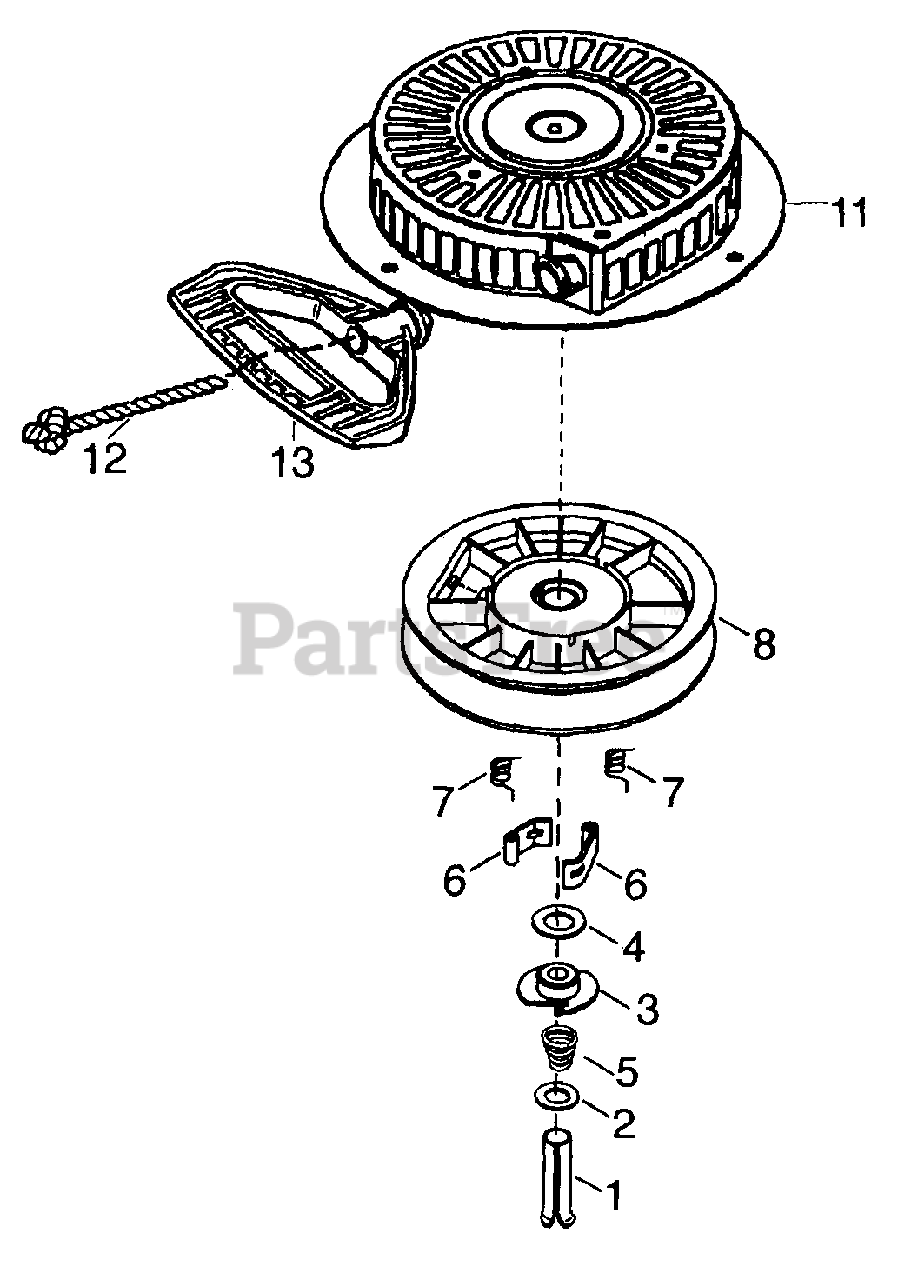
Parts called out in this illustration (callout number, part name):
5	Brake Spring
6	Starter Dog
7	Dog Spring
8	Pulley & Rewind Spring Assy
11	Starter Housing Assy
12	Starter Rope
13	Mitten Grip Handle
